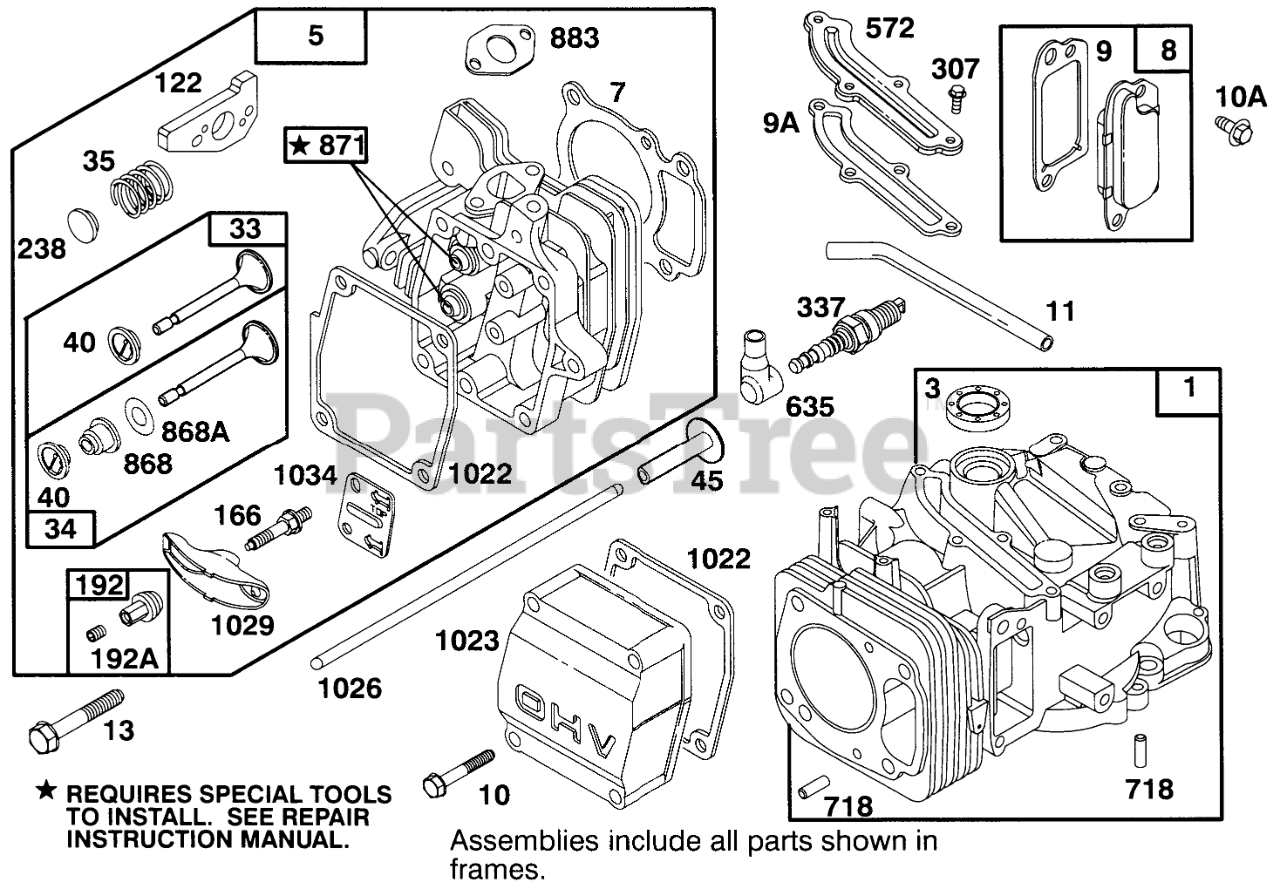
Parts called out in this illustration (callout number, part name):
1	CYLINDER ASSEMBLY
3	SEAL - OIL
5	CYLINDER HEAD
7	CYLINDER HEAD GASKET
8	Breather Assy
9	BREATHER GASKET
9A	GASKET-BREATHER
10	HEX HEAD SCREW
10A	HEX HEAD SCREW
11	TUBE - BREATHER
13	CYLINDER HEAD SCREW
33	EXHAUST VALVE
34	INTAKE VALVE
35	VALVE SPRING
40	SPRING RETAINER
45	VALVE TAPPET
122	ADAPTER ASSEMBLY
166	ROCKER ARM STUD
192	NUT - HEX SPECIAL
192A	SCREW SET
238	VALVE CAP
307	SCREW - SEM
337	PLUG-SPARK
572	BAFFLE - CYCLINDER
635	SPARK PLUG ELBOW
718	DOWEL - SLEEVE
868	SealAssy-Valve
868A	Seal-Valve
871	Bushing-Guide
883	EXHAUST GASKET
1022	ROCKER COVER GASKET
1023	COVER - VALVE
1026	PUSH ROD
1029	ROCKER ARM
1034	PUSH ROD GUIDE
